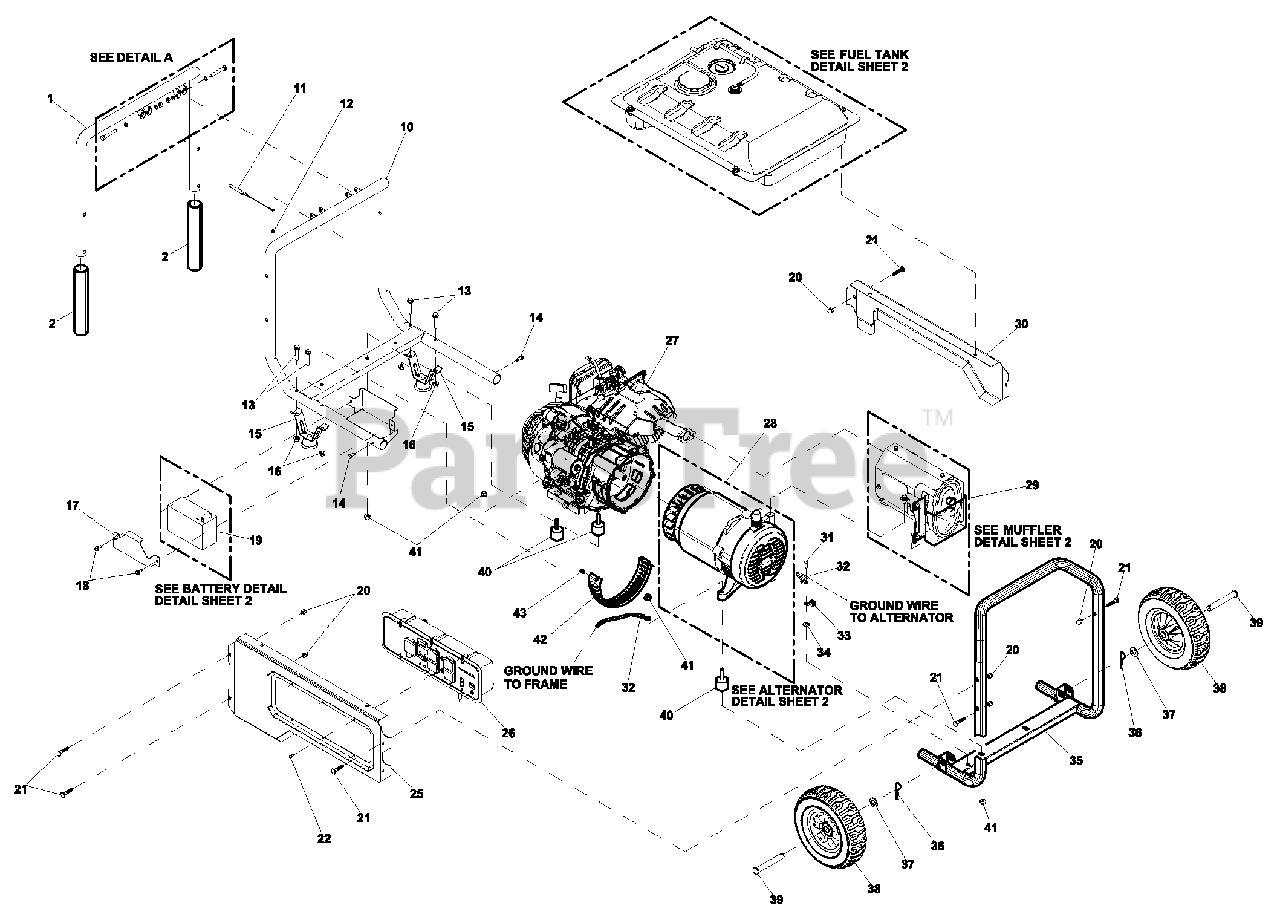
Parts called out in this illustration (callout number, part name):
1	HANDLE
2	HANDLE GRIP
10	CRADLE 389CC ENG
11	PIN QUICK RELEASE
12	SCREW HHTT M4-0.7 X 8 ZP
13	SCREW HHFC M8-1.25 X 45
14	SCREW HHSD PREMIUM 1/4-14X1 BZ
15	FOOT ASSY
16	NUT HEX FL WHIZ M8-1.25
17	BRACKET BATTERY HOLD DOWN
18	SCREW HHFCS M6-1 X 16 G8.8
19	BATTERY 12V10AH SEALED
20	CAP NUT M8-1.25 BLACK ZINC
21	CURVE HD SQ NECK M8-1.25X41LNG
22	SCREW PPPH M5-0.8 X 16 BZC
25	SIDE PANEL CONTROL
26	CONTROL PNL ASSY
27	ENGINE 389 ES W/O MFLR EPA PH3
28	ALT 6500W CU-AL BRUSH TYPE
29	ASSY MUFFLR GP5.5-6.5KW
30	SIDE PANEL, EXHAUST,
31	SCREW HHTT M6-1.0 X 20 ZINC
32	GROUND WIRE BRG CAR-LUG 4KW
33	LUG SLDLSS #2-#8 X 17/64 CU
34	WASHER LOCK SPECIAL 1/4"
35	CRADLE 389CC ALT
36	COTTER HAIRPIN 2.56 X .80
37	WASHER FLAT M16
38	WHEEL 10"D X 3" NVR FLT
39	AXLE PIN 5/8"X4 1/2",3/4" HEAD
40	VIB MOUNT 35 X 12 X M8-1.25
41	NUT HEX FL WHIZ M8-1.25
42	SCROLL ALTERNATOR
43	SCREW HHC M5-0.8 X 10 C8.8
